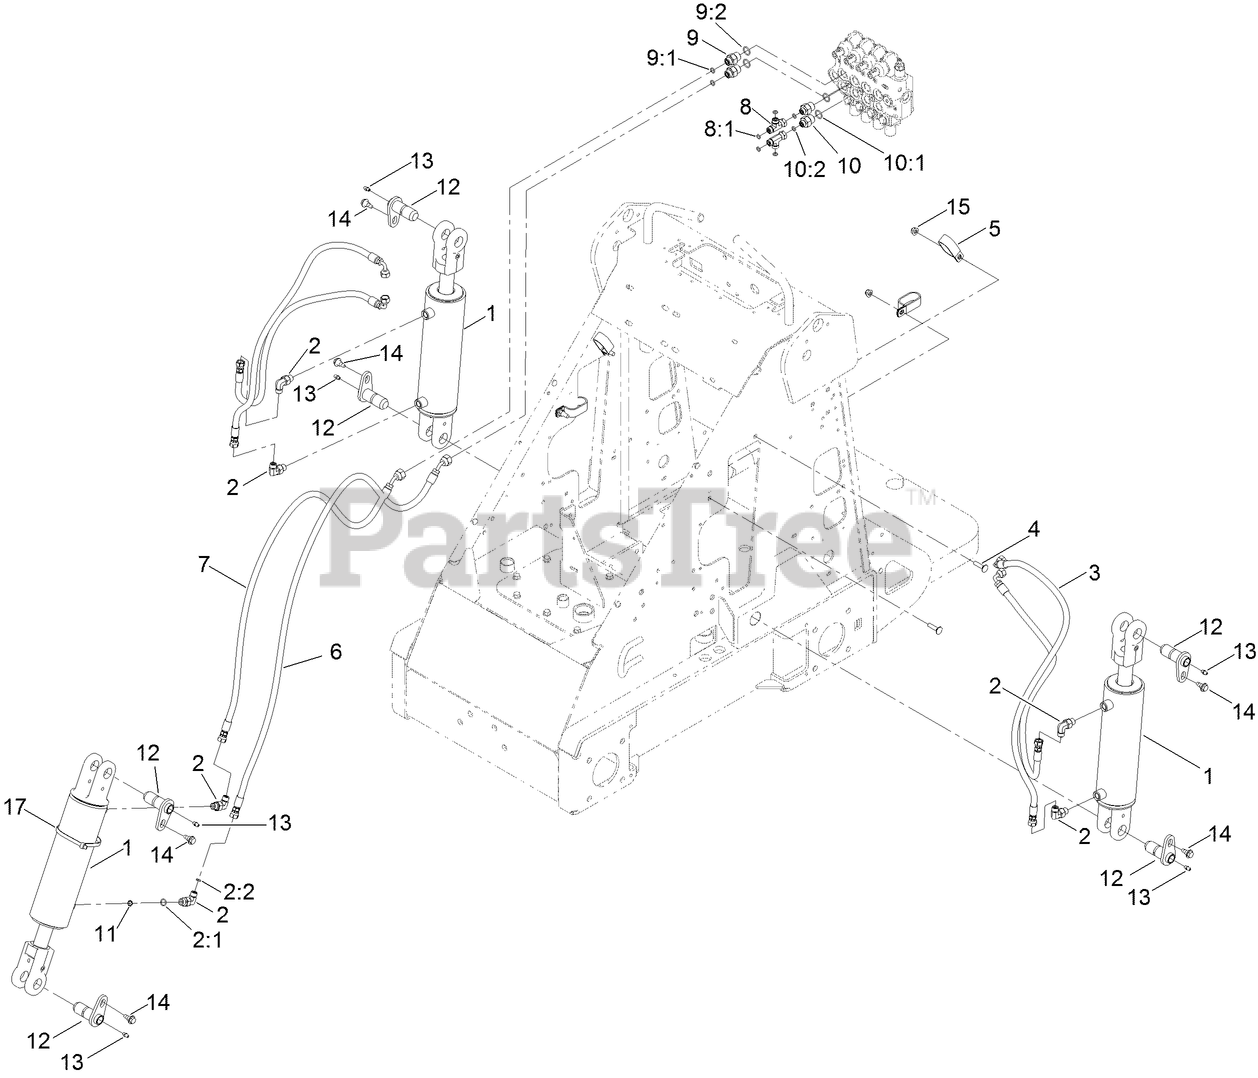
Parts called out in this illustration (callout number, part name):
1	CYLINDER-HYDRAULIC
2	FITTING-ELBOW, 90 DEG
2:1	O-RING
2:2	O-RING
3	HOSE-HYD
4	SCREW-CARR
5	CLAMP-R, DOUBLE
6	HOSE-HYD
7	HOSE-HYD
8	FITTING-HYD
9	FITTING-STRAIGHT
9:1	O-RING
9:2	O-RING
10	FITTING-STR
10:1	O-RING
10:2	O-RING
11	ORIFICE-PORT INSERT, ONE WAY
12	PIN-PIVOT
13	FITTING-GREASE
14	BOLT-SHOULDER
15	NUT-HF, NI
17	TIE-CABLE
